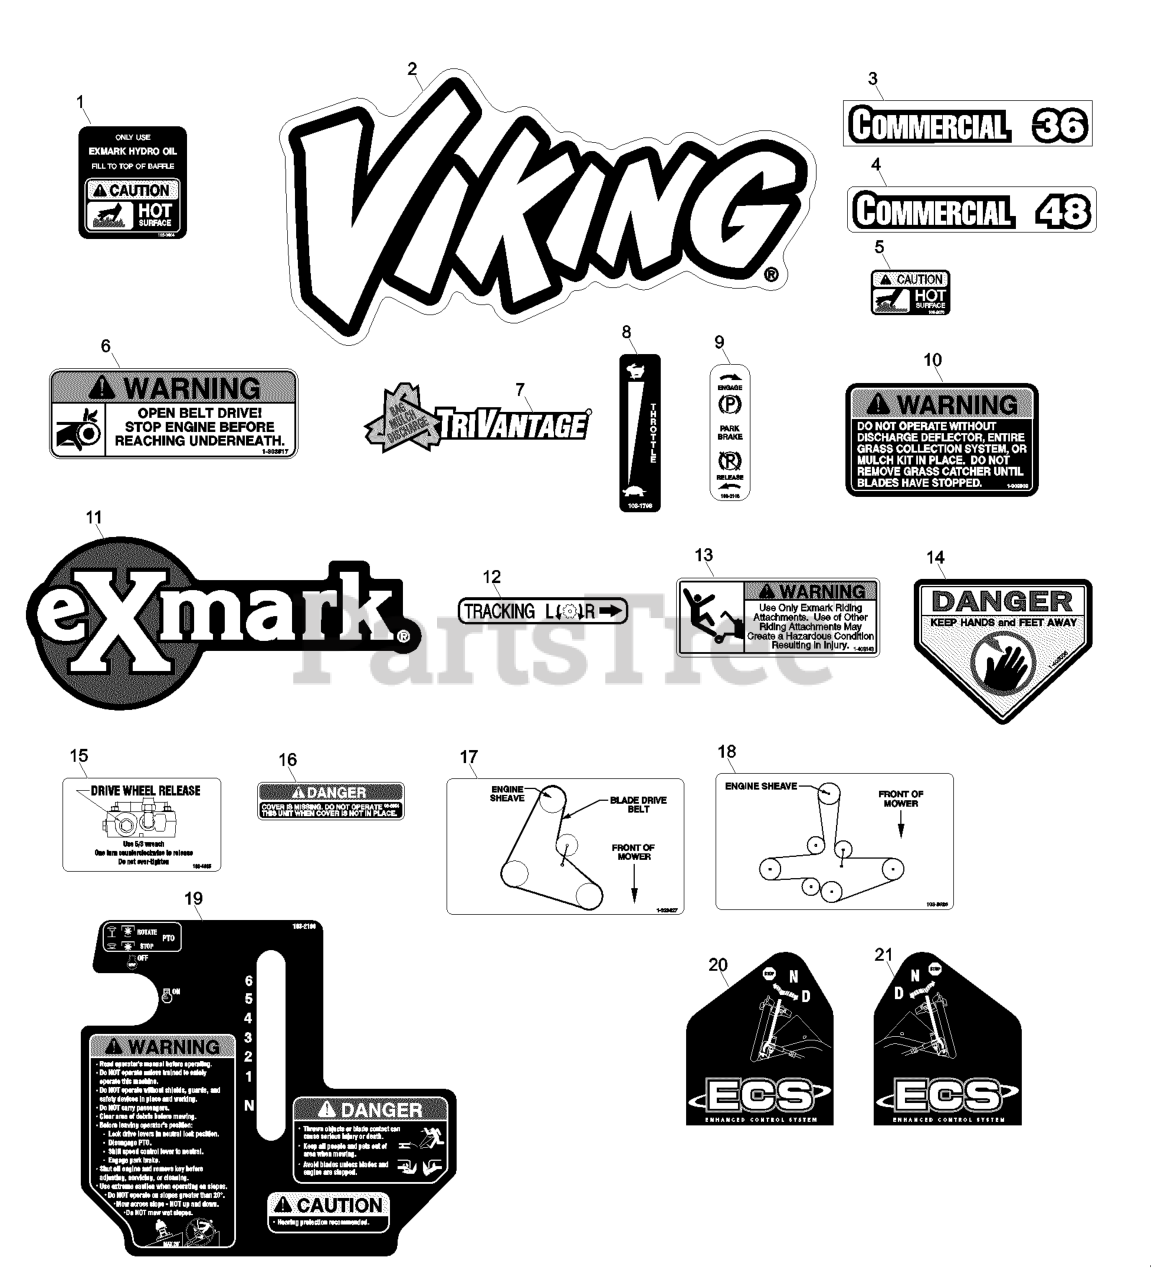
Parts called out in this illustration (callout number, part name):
1	DECAL-HYDRAULIC TANK
2	DECAL,VH MODEL
3	DECAL,COMMERCIAL 36
4	DECAL,COMMERCIAL 48
5	DECAL-CAUTION
6	DECAL,BELT DRIVE
8	DECAL,THROTTLE ONLY
9	DECAL-BRAKE, PARK
10	DECAL-WARNING, DISCHARGE
11	DECAL,EXMARK LOGO
12	DECAL,TRACKING ADJUST
13	DECAL,SULKY WARNING
14	DECAL-DANGER
15	DECAL,DRIVE RELEASE
16	DECAL-COVER, MISSING
17	DECAL,BELT ROUTING 32/36
18	DECAL,BELT ROUTING
19	DECAL,CONSOLE VH ECS
20	DECAL,LH ECS INSTRUCTION
21	DECAL,RH ECS INSTRUCTION
